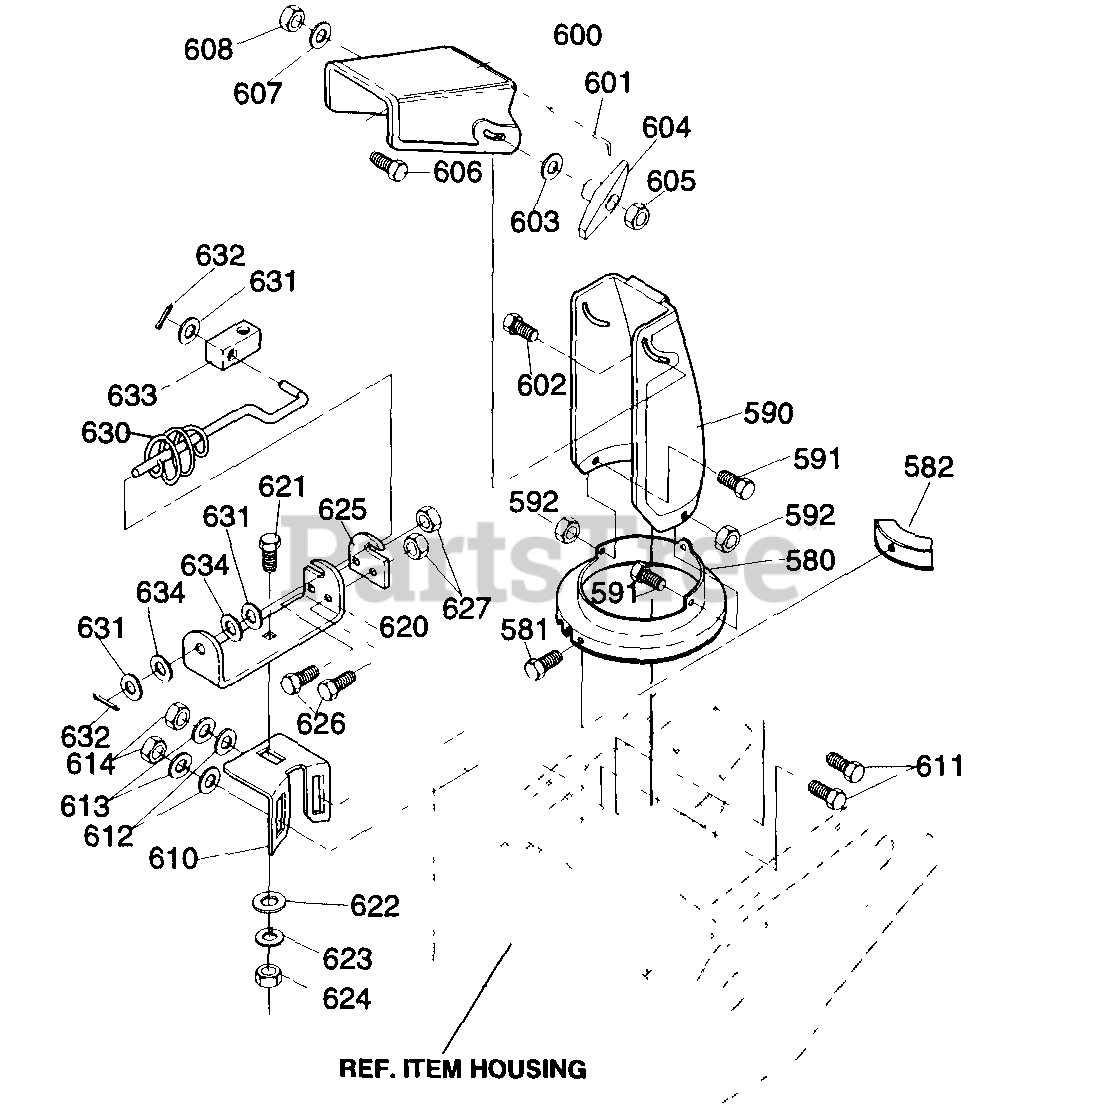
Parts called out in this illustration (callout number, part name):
580	LOWER CHUTE RING
581	SCREW 1/4-14X.63
582	CLIP, CHUTE RING
590	LOWER CHUTE
591	SCREW, 1/4-20X.50
592	NUT, 1/4-20 MAC-LOCK
600	UPPER CHUTE
601	WIRE, HINGE
602	CARR. BOLT 5/16-18X1.25
603	FLATWASHER
604	KNOB, T 2BLADE
605	NUT, 5/16-18 REGHEX
606	SCREW 5/16-18X.75
607	FLATWASHER
608	NUT, 5/16-18 RGHXCTRLK
610	BRACKET, WORM ADJUST
611	CARR. BOLT 5/16-18X.75
612	FLATWASHER
613	WASHER, HVSPTLK
614	NUT, 5/16-18 REGHEX
620	BRACKET, CHUTE ROD
621	CARR. BOLT 5/16-18X.75
622	FLATWASHER
623	WASHER, HVSPTLK
624	NUT, 5/16-18 REGHEX
625	PLATE, CHUTE ROD
626	SCREW 1/4-20X.50
627	NUT, 1/4-20 RGHXCTRLK
630	ROD, ASSY CHUTE CTRL
631	FLATWASHER
632	COTTER PIN
633	BLOCK, PIVOT
634	WASHER CURVED SPRING
